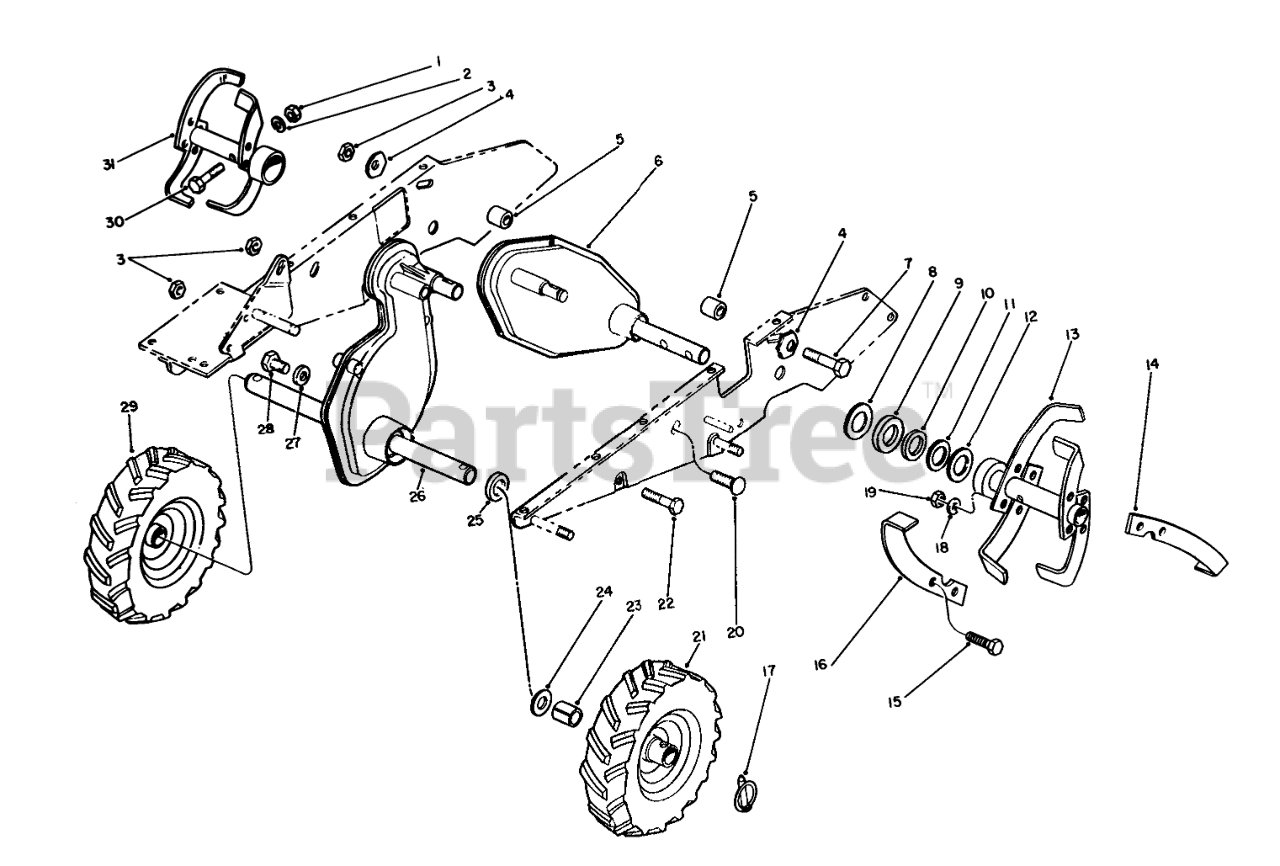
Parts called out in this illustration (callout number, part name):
1	NUT-HEX
2	WASHER-LOCK
3	NUT-LOCK, CONE
4	Pyramidal Lockwasher
5	Spacer
6	Chain Case Assy.-Tine Drive
7	Hex Hd. Capscrew
8	Washer
9	Felt Seal
10	Felt Seal
11	Washer
12	Felt Seal
13	Tine Assembly-L.H.
14	Tine-R.H.
15	Tine Bolt
16	Tine-L.H.
17	Kilk Pin
18	WASHER-LOCK
19	NUT-HEX
20	BOLT-CARR
21	Tire & Wheel Assy.-L.H.
22	SCREW-HH
23	Spacer-Wheel-Long
24	Washer
25	Seal
26	Chain Case Assembly-Wheel Drive
27	Nylon Washer
28	SCREW-HH
29	Tire & Wheel Assy.-R.H.
30	Capscrew
31	Assembly-R.H.
